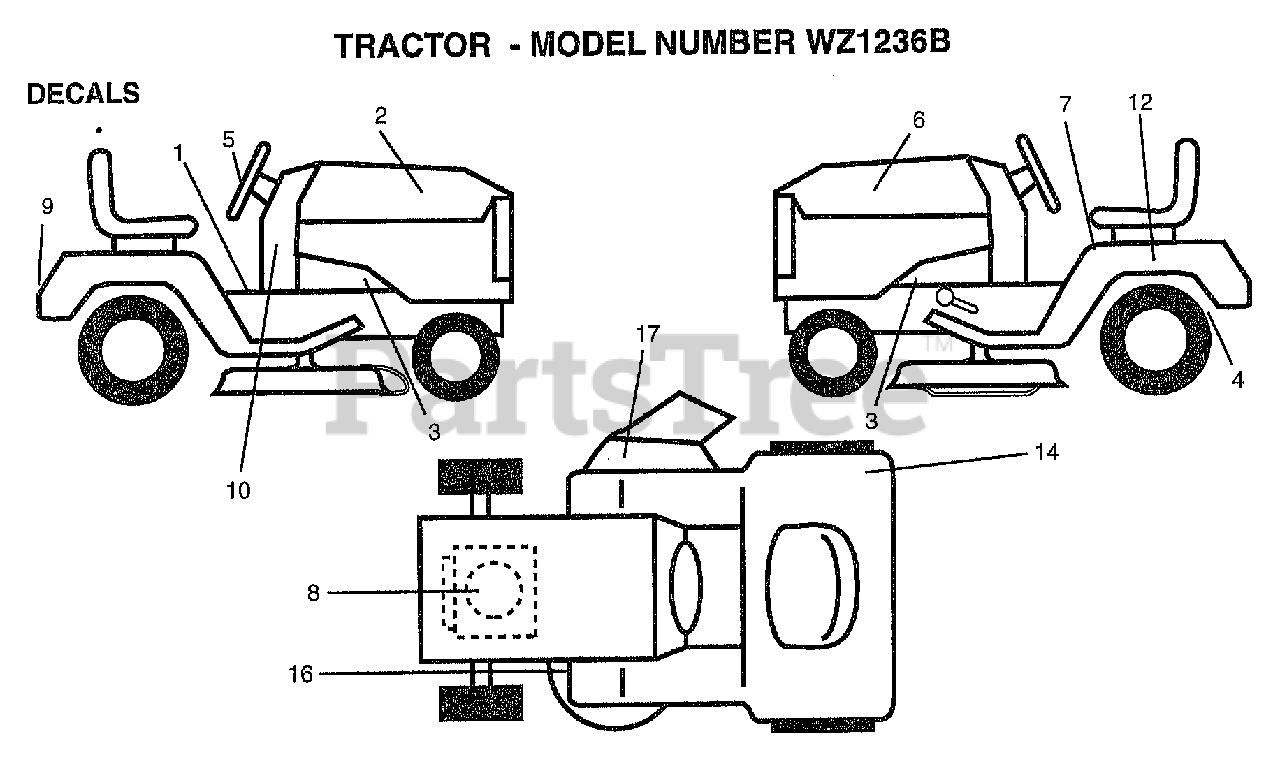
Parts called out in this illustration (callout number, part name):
1	DECAL CLUTCH/BRAK
2	DECAL.HOOD.RH
3	"DECAL CHASSIS,HOT"
4	DECAL.DRAWBAR.LDL
5	DECAL.INS.STRG/WH
6	DECAL.HOOD.LH
7	DECAL.READ.O.MANU
9	DECAL.FENDER
10	DECAL.EURO.ST.CE.
12	DECAL.BATRY.3-3908
16	DECAL.DANGER.CUTF
17	DECAL.V.BELT
